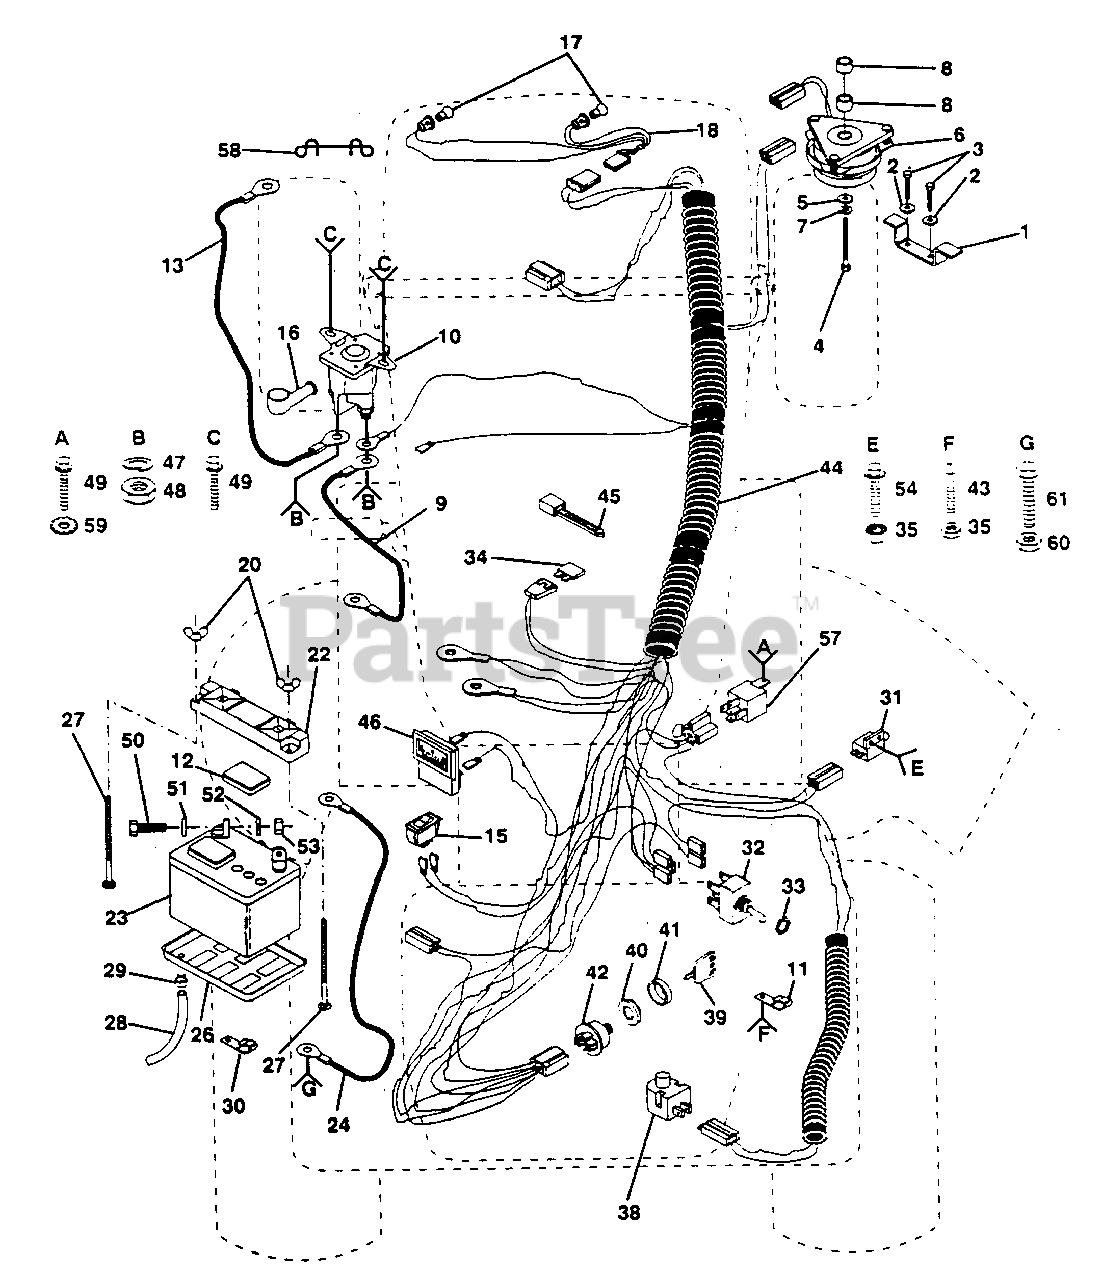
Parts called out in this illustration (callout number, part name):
1	Stop, Clutch (AYP part number)
2	Washer, Lock 3/8 (AYP part number)
3	Bolt, Hex 3/8-16 x 3,4 (AYP part number)
4	Bolt, Hex 7/16-20 x 1-1/2 Grade 5
5	Washer (AYP part number)
6	Clutch, Electric (AYP part number)
7	Washer, Lock 7/16 (AYP part number)
8	Spacer, Clutch (AYP part number)
9	Cable, Battery (AYP part number)
10	Solenoid (AYP part number)
11	Clip, Insulated (AYP part number)
12	Battery, Caps (AYP part number)
13	Cable, Starter (AYP part number)
15	Switch, Light (AYP part number)
16	Cover, Terminal (AYP part number)
17	Bulb, Light (AYP part number)
18	Harness, Light Socket (AYP part number)
20	Nut, Wing 1/4-20 (AYP part number)
22	Guard, Terminal (AYP part number)
23	Battery (AYP part number)
24	Cable, Ground (AYP part number)
26	Tray, Battery (AYP part number)
27	Bolt, Carriage 1/4-20 x 7-1/2 (AYP part number)
28	Tube, Plastic (AYP part number)
29	Clamp, Hose (AYP part number)
30	Clip (AYP part number)
31	Switch, Interlock (AYP part number)
32	Switch, P.T.O.
33	Nut, Hex (AYP part number)
34	Fuse (AYP part number)
35	Nut, Keps #10-32 (AYP part number)
38	Switch, Seat (AYP part number)
39	Key (AYP part number)
40	Nut. Ignition (AYP part number)
41	Bezel. Ignition (AYP part number)
42	Switch. Ignition (AYP part number)
43	Screw. Slot Pan Hd. #10-32 x 1/2 (AYP part number)
44	Harness. Ignition
45	Cable. Tie (AYP part number)
46	Ammeter (AYP part number)
47	Washer. Lock 1/4 (AYP part number)
48	Nut, Hex Jam 1/4-20 (AYP part number)
49	Screw, Hex Washer Hd. Thd. Cutting 1 4-20 x 1/2 (AYP part number)
50	Bolt, Hex 1/4-20 x 3/4 (AYP part number)
51	Washer 9/32 x 5/8 x 16 Ga. (AYP part number)
52	Washer, Lock 1/4 (AYP part number)
53	Nut, Hex 1/4-20 (AYP part number)
54	Screw, Hex Washer Hd. #10-32 x 1-1/2 (AYP part number)
57	Assembly, Relay (AYP part number)
58	Tie, Wire (AYP part number)
59	Washer, Lock Ext. Tooth 3/8 (AYP part number)
60	Nut, Crownlock 3/8
61	Bolt, Hex, Fin 3/8-16 x 3/4 (AYP part number)
